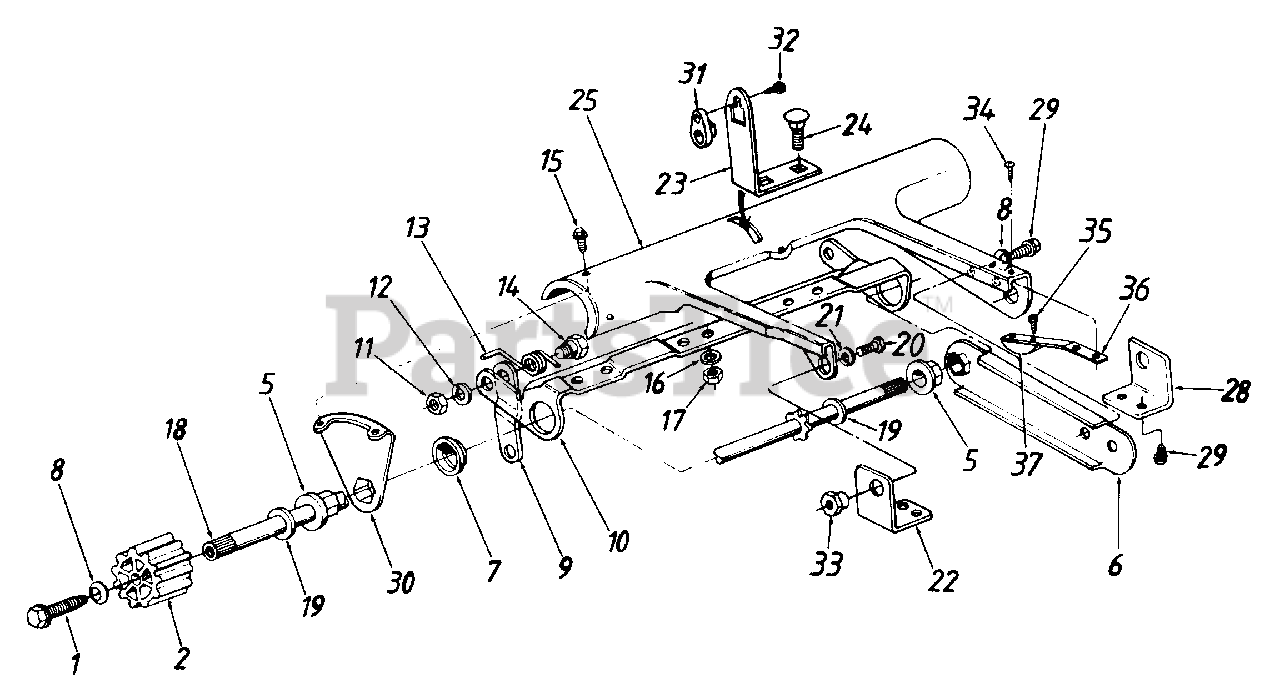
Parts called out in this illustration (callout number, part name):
1	Hex Scr. 1/4 - 20 x .62" Lg. (Gr. 5)
2	Wheel Drive Pinion
5	Hex Flange Brg. .504" I.D.
8	Bell-Wash. .265" I.D. x .75" O.D.
11	Hex Nut 5/16 - 18 Thd.
12	L-Wash. 5/16" I.D.
13	Torsion Spring - R.H.
14	Shoulder Bolt .437" Dia.
15	Hex Hd. AB-Tap Scr. 1/4" x .62" Lg.
16	L-Wash. 1/4" I.D.
17	Hex Nut 1/4 - 20 Thd.
18	Drive Shaft Ass'y.
19	Fl-Wash. .531" I.D. x .93" O.D.
20	Hex Bolt 3/8 - 16 x .5" Lg.
21	L-Wash. 3/8" I.D.
32	Hex B-Tap Scr. #10 x .44" Lg.
33	Shld. Nut .625" Dia. x .165" Lg.
34	Truss Mach. B-Tap Scr. #10 x .5" Lg.
35	Hex Wash. B-Tap Scr. #10 x 3/8" Lg.
36	Cantilever Spring
37	Chain Tensioner
